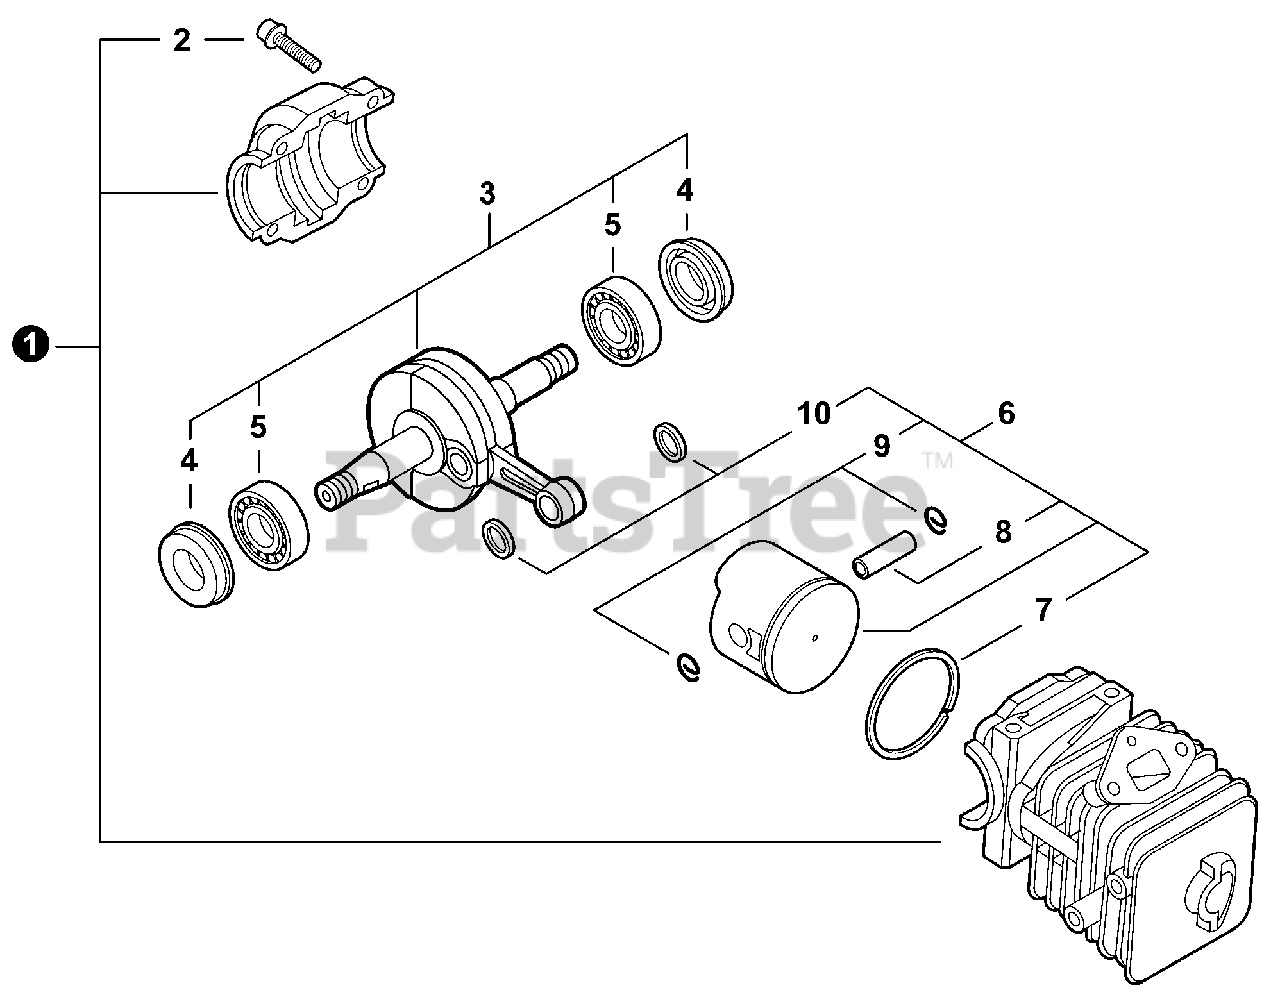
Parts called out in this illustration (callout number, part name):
1	CYLINDER KIT
2	BOLT 5×22
3	CRANKSHAFT ASSY
4	SEAL, OIL 12
5	BEARING, BALL 6001
6	PISTON KIT
7	RING, PISTON
8	PIN, PISTON
9	RING, SNAP
10	WASHER, THRUST 8.2×13×0.5
